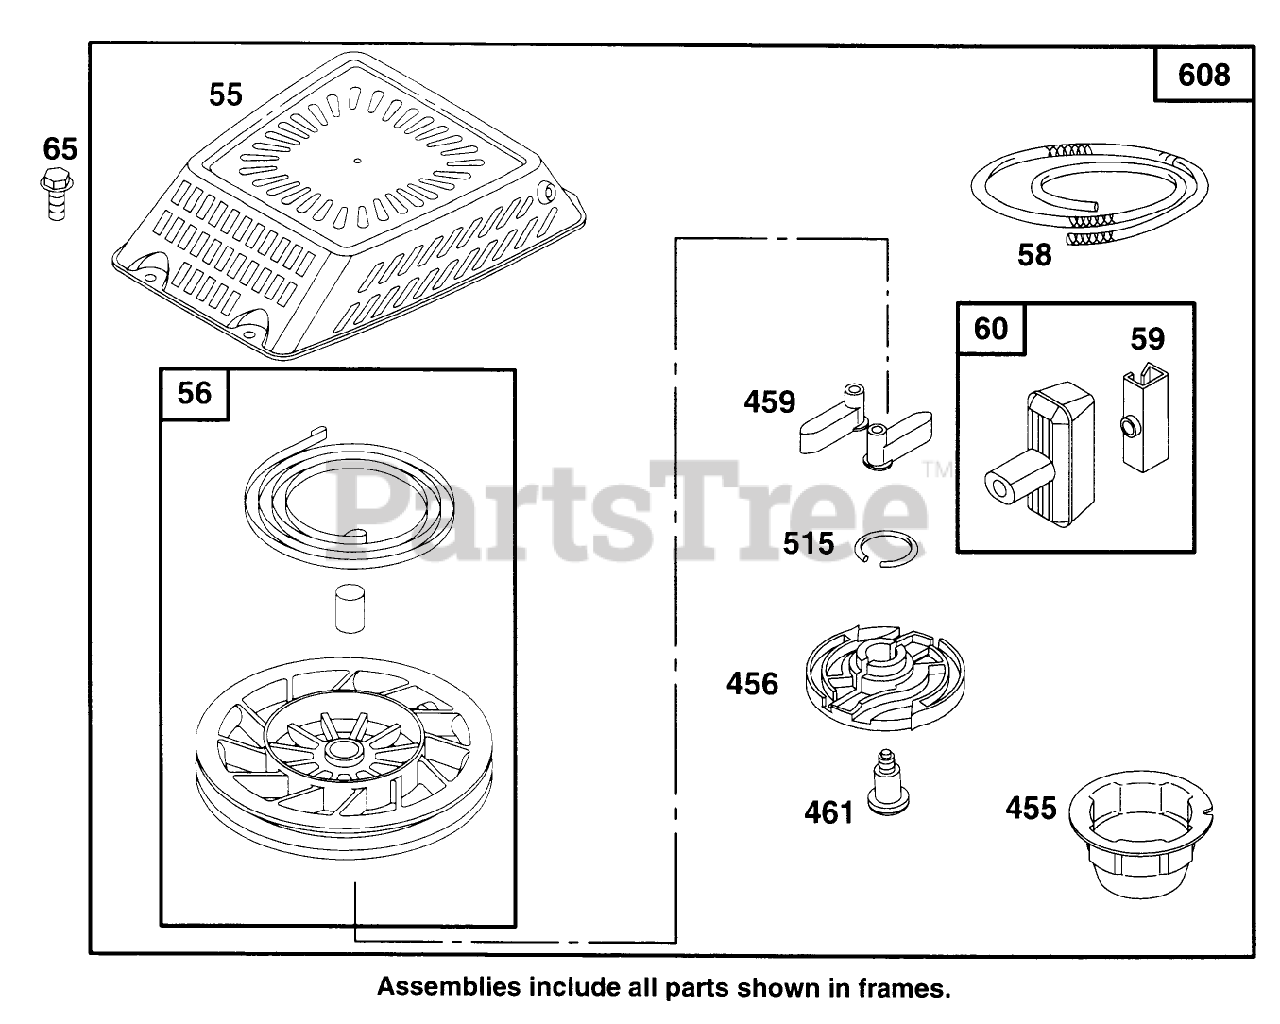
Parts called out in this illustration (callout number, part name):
59	INSERT-HANDLE, REWIND
455	CUP - STARTER
456	RETAINER - SPRING
459	PAWL-STARTER
515	SPRING-TORSION
